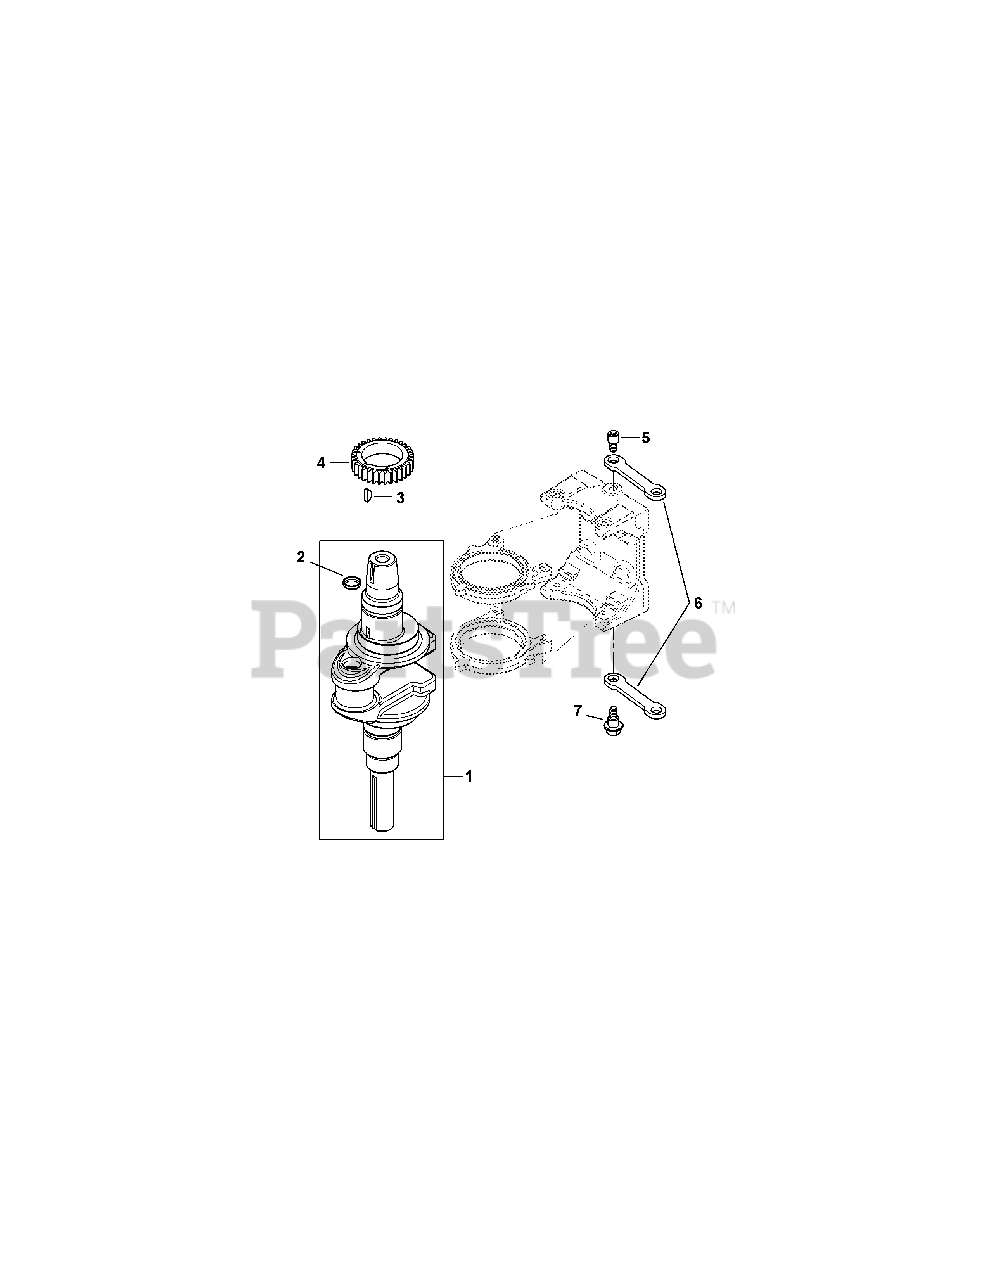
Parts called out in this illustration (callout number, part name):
1	Crankshaft Assembly Kit (Inc. 2)
3	Key, 3/16 X 5/8
4	Crankshaft Gear
5	Link Pivot Screw
6	Balance Weight Linkage
7	Shoulder Screw
